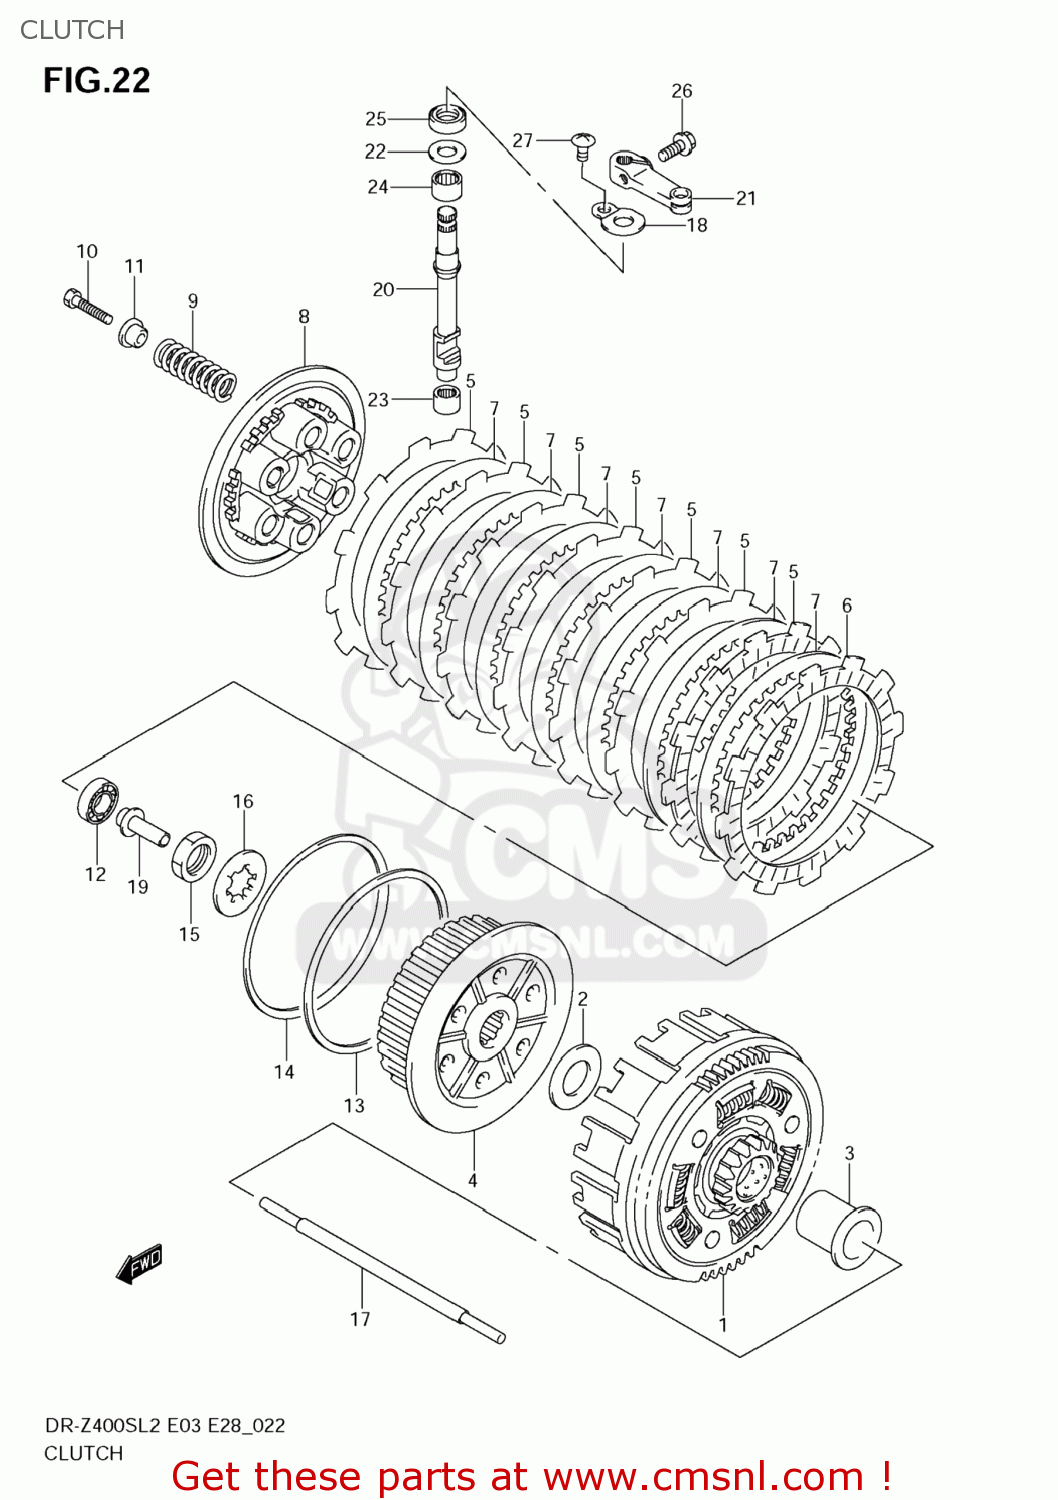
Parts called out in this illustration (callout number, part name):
1	GEAR ASSY,PRI DRIVEN
2	WASHER
3	SPACER,PRIMARY DRIVEN GEAR
4	HUB,CLUTCH SLEEVE
5	PLATE,CLUTCH DRIVE NO.1 (NAS)
6	PLATE,CLUTCH DRIVE NO.2 (NAS)
7	PLATE,CLUTCH DRIVEN (NAS)
8	DISC,CLUTCH PRESSURE
9	SPRING,CLUTCH
10	BOLT
11	WASHER
12	BEARING(12X28X8)
13	WASHER(112X122X1)
14	WASHER
15	NUT
16	WASHER,LOCK
17	ROD,CLUTCH PUSH
18	RETAINER,CL RLSE OIL SEAL
19	PIECE,CL PUSH
20	CAMSHAFT,CLUTCH RELEASE
21	ARM,CLUTCH RELEASE
22	SHIM(10X20X1)
23	BEARING(10X14X10)
24	BEARING(12X16X10)
25	SEAL,OIL(10X20X6)
26	BOLT
27	SCREW
